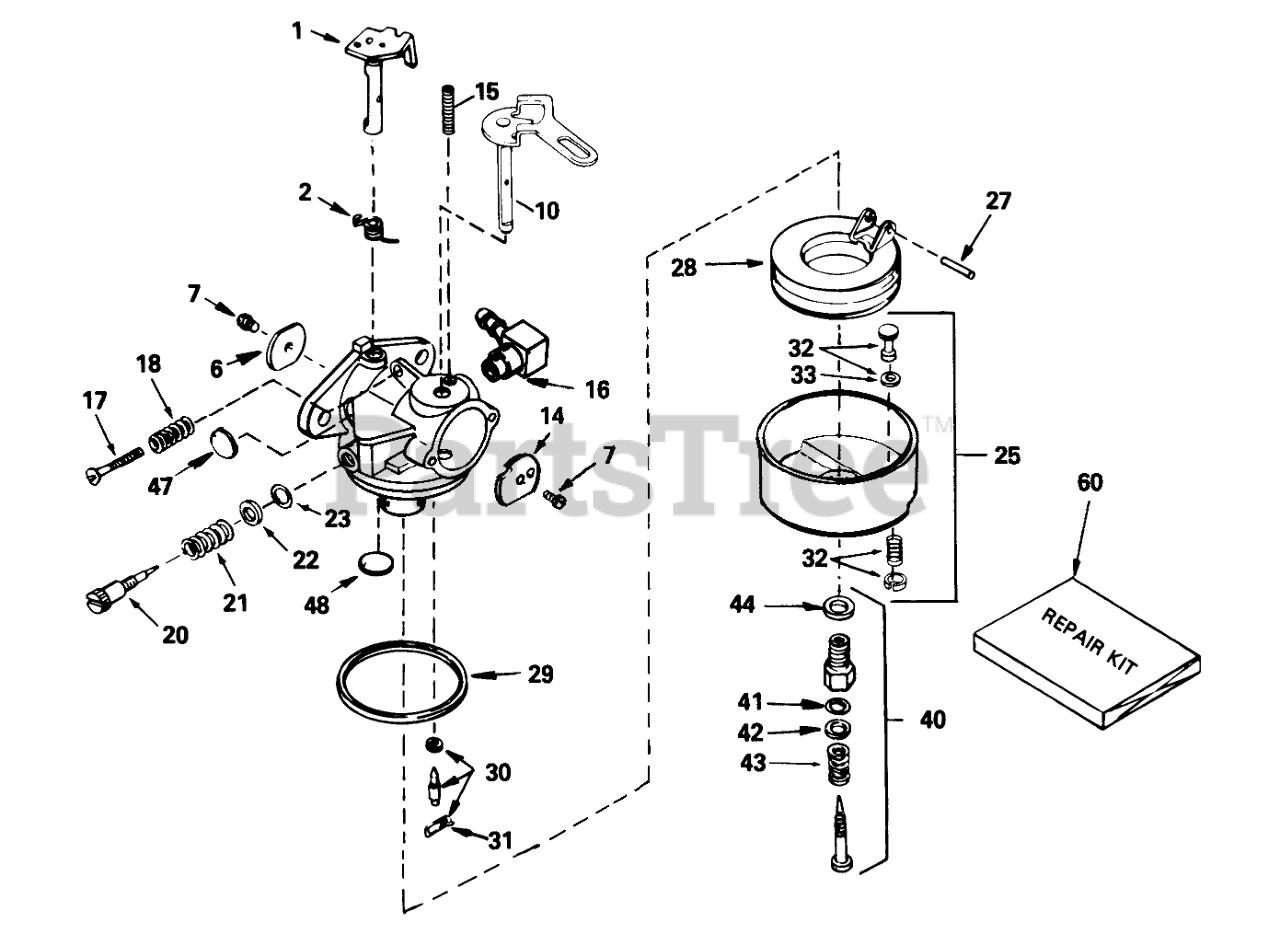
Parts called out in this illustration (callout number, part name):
1	Throttle Shaft and Lever ASM
2	Spring-Return, Throttle
6	Shutter-Throttle
7	Screw-Shutter
10	Choke Shaft and Lever Asm
14	Shutter-choke
15	Spring-Positioning, Choke
16	Fitting-Fuel
17	Screw-Throttle Crack Screw / Idle Speed
18	Spring-Tension
20	Screw-Idle
21	Spring-Tension
23	"O"Ring
25	Bowl-Assembly (Incl. Ref. #32 & 33)
27	Shaft-Float
28	Float
29	O Ring-Bowl, Float
30	Inlet Needle-Seat & Clip (Incl. Ref. #31)
31	Clip-Spring
32	Drain Assembly-Bowl (Incl. Ref. #33)
33	Gasket-Plunger, Drain
40	Screw Adjustment Assembly (Incl. Ref. #41-44)
41	"O"Ring
44	Washer-Bowl Nut
47	Plug-Welch, Idle Mixture Well
48	Plug-Welch, Atmospheric Vent
60	Kit-Repair
